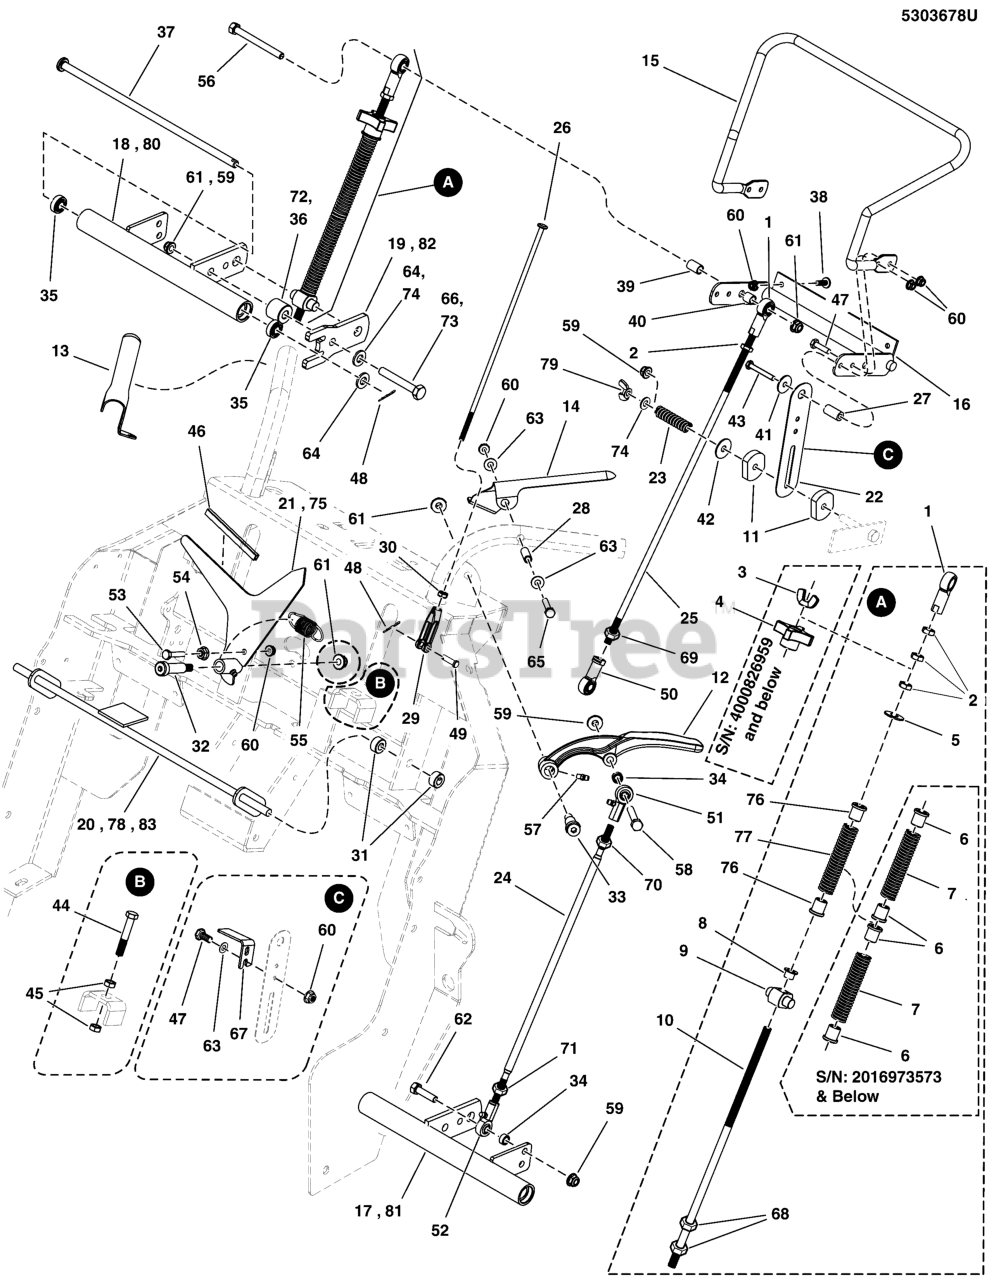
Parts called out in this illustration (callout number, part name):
1	BALL JOINT, 3/8-24 FEMALE
2	NUT, 3/8-24 HEX
3	WING NUT, 3/8-24, CZ
4	KNOB, 4 ARM, 3/8-24
5	WASHER, 3/8 USS
6	BUSHING, .38 X .75 X .75, PLASTIC
7	SPRING-COMP, .615ID X 4.00LG X .080WR
8	BUSHING, .38ID X .47 OD X .38L, FL
9	TRUNION, 1/2" POSTS, STAINLESS
10	ROD, CONTROL SYSTEM, WALK
11	PAD, T-712 FRICTION MATERIAL
12	HANDLE, REVERSING - BLK
15	BAR, SPEED CONTROL - BLK
17	WELD, CENTER PIVOT HUB, LH - WALK - BLK
18	WELD, CENTER PIVOT HUB, RH - WALK - BLK
19	TAB, CONTROL PIVOT - BLK
20	WELD, OPC ROD, WALK - BLK
21	SENSOR, Speed
22	PLATE, FRICTION CONTROL, SS
23	SPRING, COMP, .40 X .60 X 2.25, BLACK
24	ROD, 5/16-24 X 15.48, LH-RH, CZ
25	ROD, 3/8-24, 19.00, LH-RH CZ
26	ROD, OPC LINK, SNP PRO WB
27	SPACER, .26 X .50 X 1.00
28	SPACER, .26 X .38 X 1.25, CZ
30	HN, 1/4F GR5 YZ
31	COLLAR, 3/8 SET
32	BOLT-3/8-16 x 1-1/2, 1/2 SHOULDER
33	BOLT, 3/8-16 X 1/2, 1.00 SHOULDER, CZ
34	SPACER, .33 X .50 X .25, CZ
35	BEARING, .375" ID X .875" OD X .341" THK
36	SPACER, .39 X 1.00 X .88, CZ
37	ROD, 3/8 X 12, HEADED - CZ
38	SCREW-TRUSS HD TORX DR 1/4-20X0.750 BLK
39	SPACER, .38 X .50 X .75
40	SPACER, .38 X .50 X .50
41	WASHER, 1/4 FENDER
42	WASHER, 5/16 FENDER
43	BOLT, 1/4-20 X 2", GD5
44	BOLT, 1/2-20 X 2-1/2, FLT
45	NUT, 1/2-20 HEX JAM
46	U-CHANNEL, RPVC #6236 X 4"
47	BOLT-1/4-20 X 3/4 GD5 YZ
48	PIN, COTTER, 1/8 X 1-1/4
49	PIN, CLEVIS, 1/4 X 7/8, PLATED
50	BALL JOINT, 3/8-24 FEMALE, LH
51	BALL JOINT 5/16-24 RH FEMALE BRONZE RACE
52	BALL JOINT 5/16-24 LH FEMALE BRONZE RACE
53	BOLT, 1/4-20 X 1-1/4, GD5
54	NUT, 1/4-20 HEX SERR. FLANGE
55	SPRING, EXT, 0.525 X 0.058 X 2.250 SS
56	BOLT, 3/8-16 X 3" GD5 CZ
57	GREASE FITTING, 1/4-28 STRAIGHT
58	BOLT, 5/16-18 X 2-1/4 GD5 YZ
59	NUT, 5/16-18 HEX NYLOCK FLANGE
60	NUT, 1/4-20 HEX NYLOCK FLANGE
61	NUT, 3/8-16 HEX NYLOCK FLANGE
62	BOLT, 5/16-18 X 1-1/4, GD5
63	WASHER, 1/4 SAE
64	WASHER, 3/8 SAE
65	BOLT, 1/4-20 X 1-3/4 GD5 YZ
66	BOLT, 3/8-16 X 2, GD5, CZ
67	BRACKET, SWITCH ENGAGEMENT - BLK
68	NUT, 3/8-16 HEX
69	NUT, 3/8-24 HEX, LH
70	NUT, 5/16-24 HEX
71	NUT, 5/16-24 HEX, LH
72	SPACER, .33 X 1.00 X .88, CZ
73	BOLT, 5/16-18 X 2 GD5
74	WASHER, 5/16" SAE
75	WELD, SPEED INDICATOR, LOCKOUT - BLK
76	FLANGED BUSHING, 3/8IDX.63ODX.8125FL
77	SPRING,COMP,.645IDX8.00LGX.080WR,BLK E-C
78	WELD, OPC ROD, WALK - BLK
79	NUT, Wing, 5/16-18
80	WELD, W35 CONTROL PIVOT, RH - BLK
81	WELD, W35 CONTROL PIVOT, LH - BLK
82	TAB, PIVOT, W35 - BLK
83	WELD, OPC ROD, WALK BEHIND - BLK
